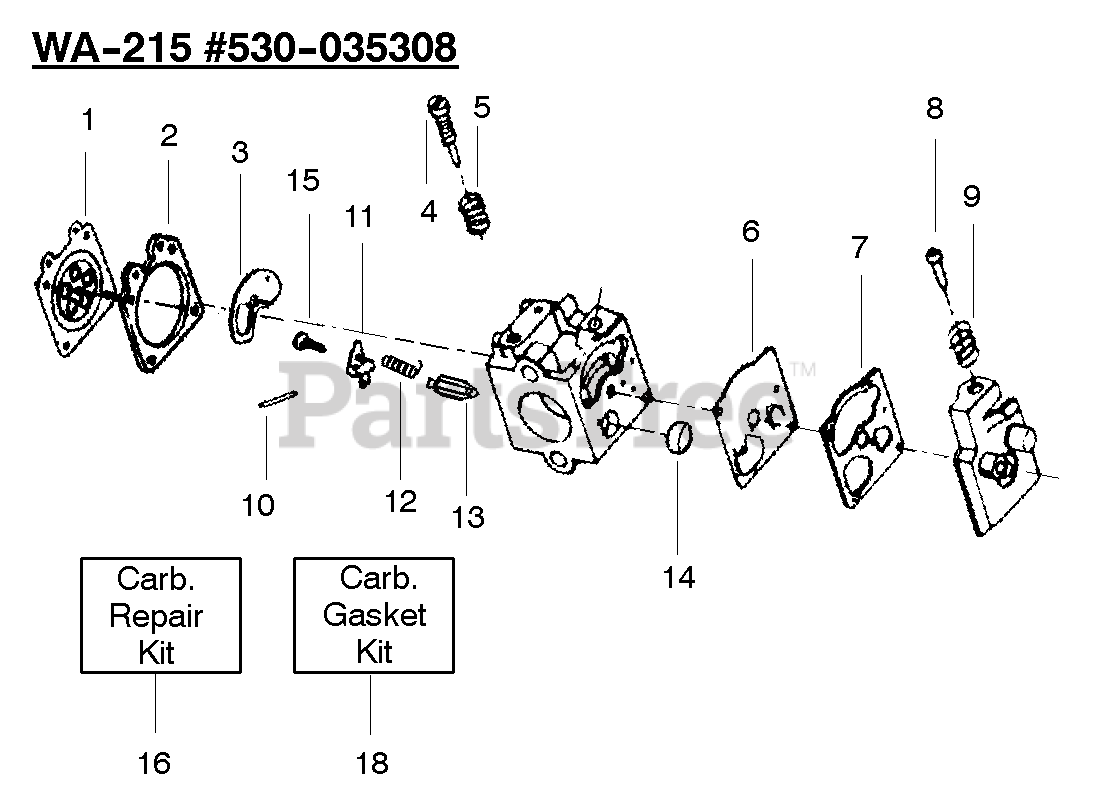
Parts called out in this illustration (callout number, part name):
1	Metering Diaphram
2	Metering Diaphragm Gasket
3	Circuit Plate Gasket
4	Mixture Needle
5	Mixture Needle Spring
6	Fuel Pump Diaphragm
7	Fuel Pump Gasket
8	Idle Speed Screw
9	Idle Speed Spring
10	Metering Lever Pin
11	Metering Lever
12	Metering Lever Spring
13	Inlet Needle Valve
14	Fuel Inlet Screen
15	Metering Lever Pin Screw
16	Carb. Kwik Repair Kit
17	Carb. Gasket/Diaphragm Kit
530-035308	Carburetor Assembly WA-215
